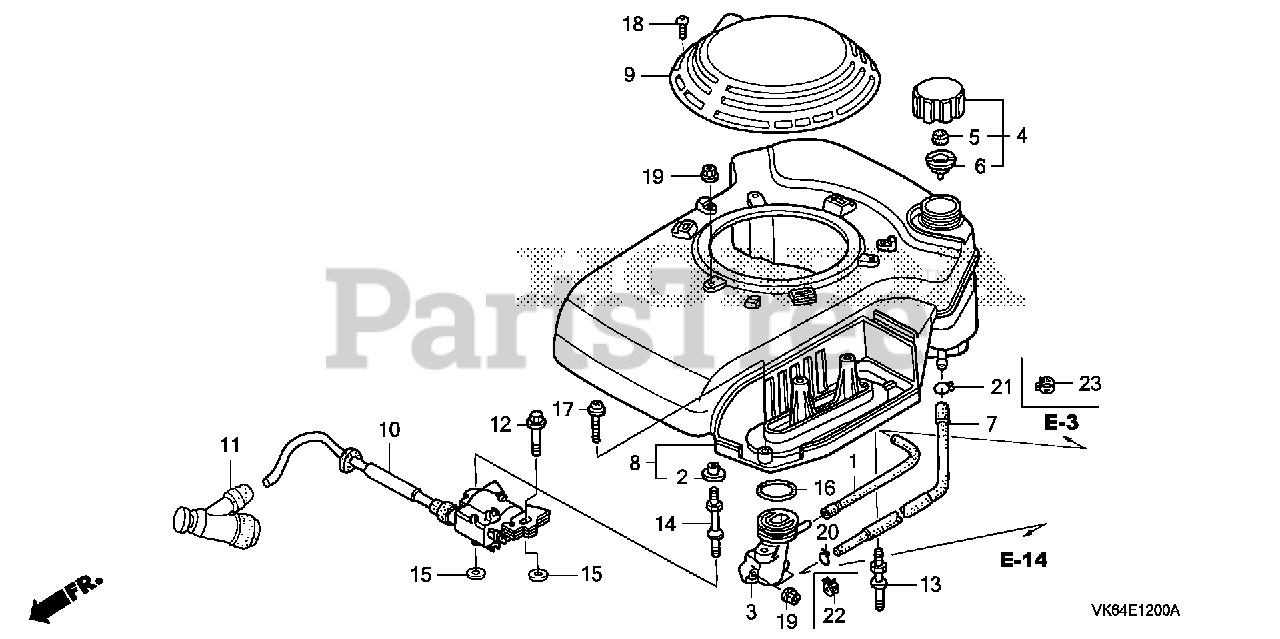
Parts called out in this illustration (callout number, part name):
1	TUBE, BREATHER
2	COLLAR, AIR CLEANER (TOYO ROKI)
3	ELBOW, AIR CLEANER
4	CAP ASSY., FUEL TANK
5	SPONGE, FUEL CAP BREATHER
6	GASKET, FUEL CAP
7	TUBE ASSY., FUEL TANK
7	TUBE ASSY., FUEL TANK (FKM)
8	COVER, FAN *R280* (POWER RED)
9	HOOD, FAN COVER *R280* (GRAINED FINISH) (POWER RED)
10	COIL ASSY., IGNITION
11	CAP ASSY., NOISE SUPPRESSOR
12	BOLT, FLANGE (6X28) (CT200) Use up to Engine SN 1530314.
13	BOLT A, STUD
14	BOLT, STUD (IGNITION COIL)
15	WASHER, PLAIN (6MM)
16	O-RING (33.3X3.5)
17	SCREW-WASHER (6X35)
18	SCREW, TAPPING (4X20)
19	NUT, FLANGE (6MM)
20	CLIP, TUBE (B8)
21	CLIP, TUBE (C9)
22	CLIP, TUBE (D8)
23	CLIP, TUBE (D8.5)
